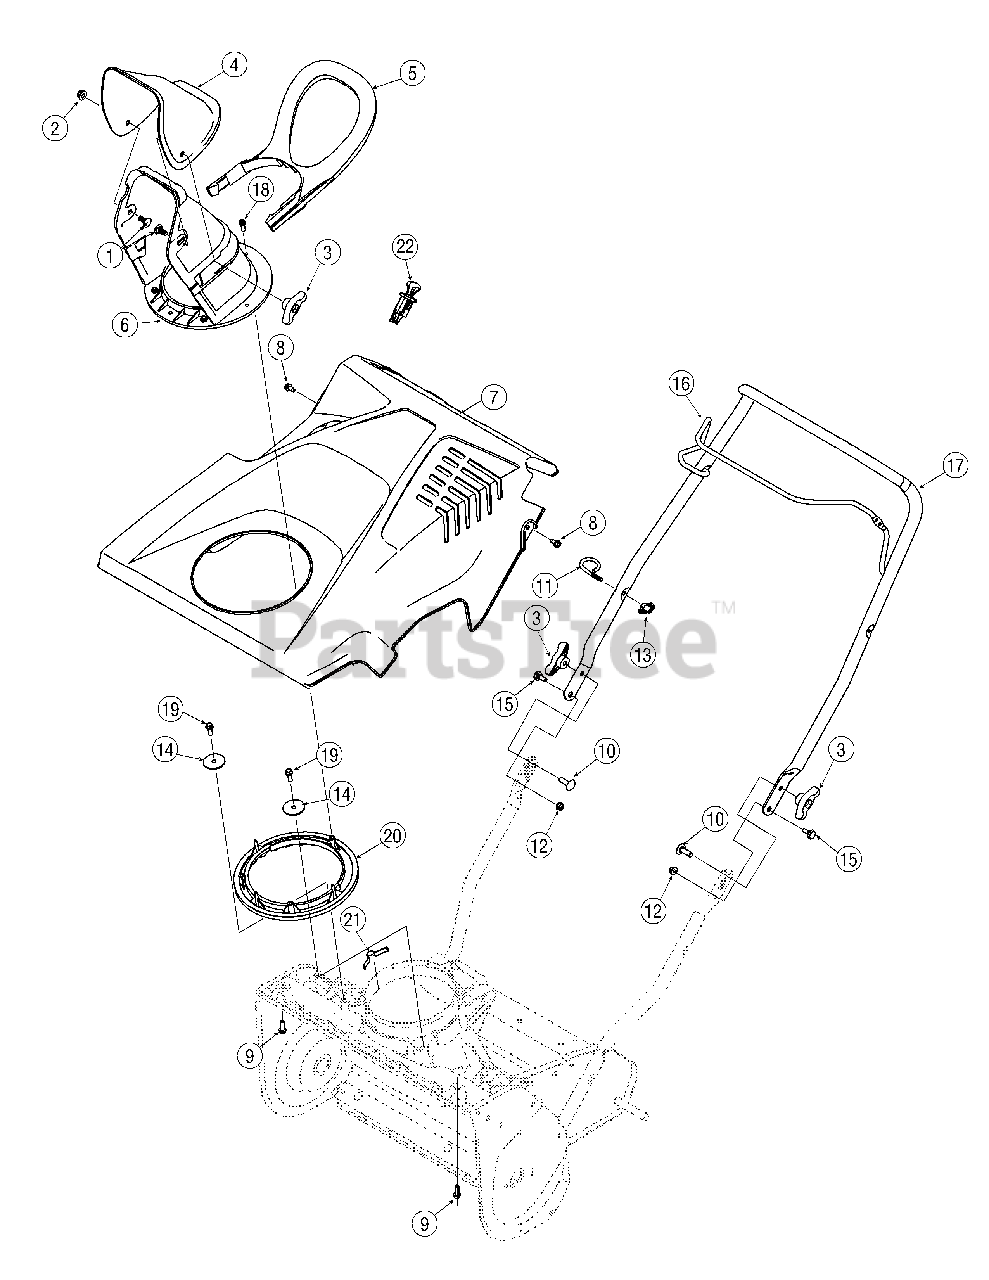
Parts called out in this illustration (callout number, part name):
1	Carriage Bolt, 5/16-18 x .750
2	Flange Lock Nut, 5/16-18
3	Wing Knob, 5/16-18
4	Upper Chute
5	Chute Handle
6	Lower Chute
7	Cover Assembly
8	Hex Washer Screw, 1/4-20 x .500
9	Hex Washer Screw, 1/4-15 x .750
10	Carriage Screw, 5/16-18 x 1.00
11	Eye Bolt, 1/4-20
12	Flange Lock Nut, 1/4-20
13	Handle Knob, 1/4-20
14	Wing Knob, 5/16-18
15	Shoulder Screw, 1/4-20 x .375 x .148
18	Hex Washer Screw, 1/4 x .750
19	Hex Washer Screw, 1/4-15 x .750
20	Chute Ring
21	Chute Adjustment Spring
22	Ignition Switch Assembly
